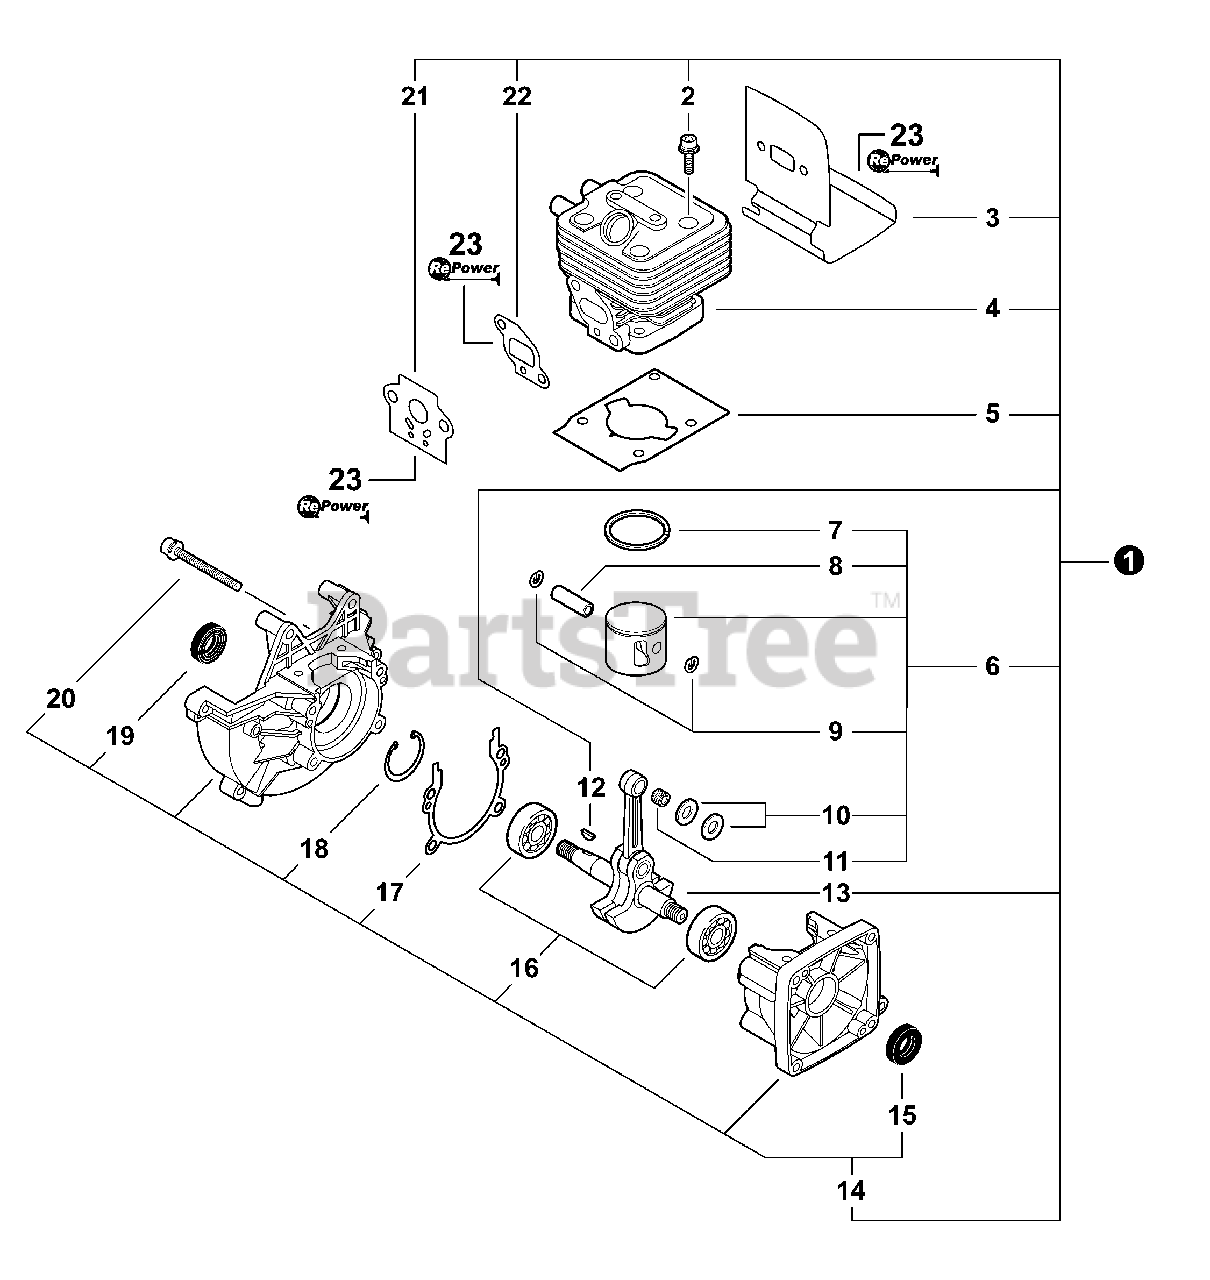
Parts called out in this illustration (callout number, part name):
1	SHORT BLOCK
2	SCREW 5×25
3	HEAT SHIELD, EXHAUST
4	CYLINDER
5	GASKET, CYLINDER
6	PISTON KIT
7	RING, PISTON
8	PIN, PISTON
9	RING, SNAP
10	WASHER, THRUST 8
11	BEARING, NEEDLE 9
12	KEY, WOODRUFF
13	CRANKSHAFT ASSY
14	CRANKCASE KIT
15	SEAL, OIL 12
16	BEARING, BALL - 6201 C3
17	GASKET, CRANKCASE
18	RING, SNAP Ø32
19	SEAL, OIL 12
20	BOLT 5×28
21	GASKET, INTAKE
22	GASKET, INTAKE
23	GASKET KIT
